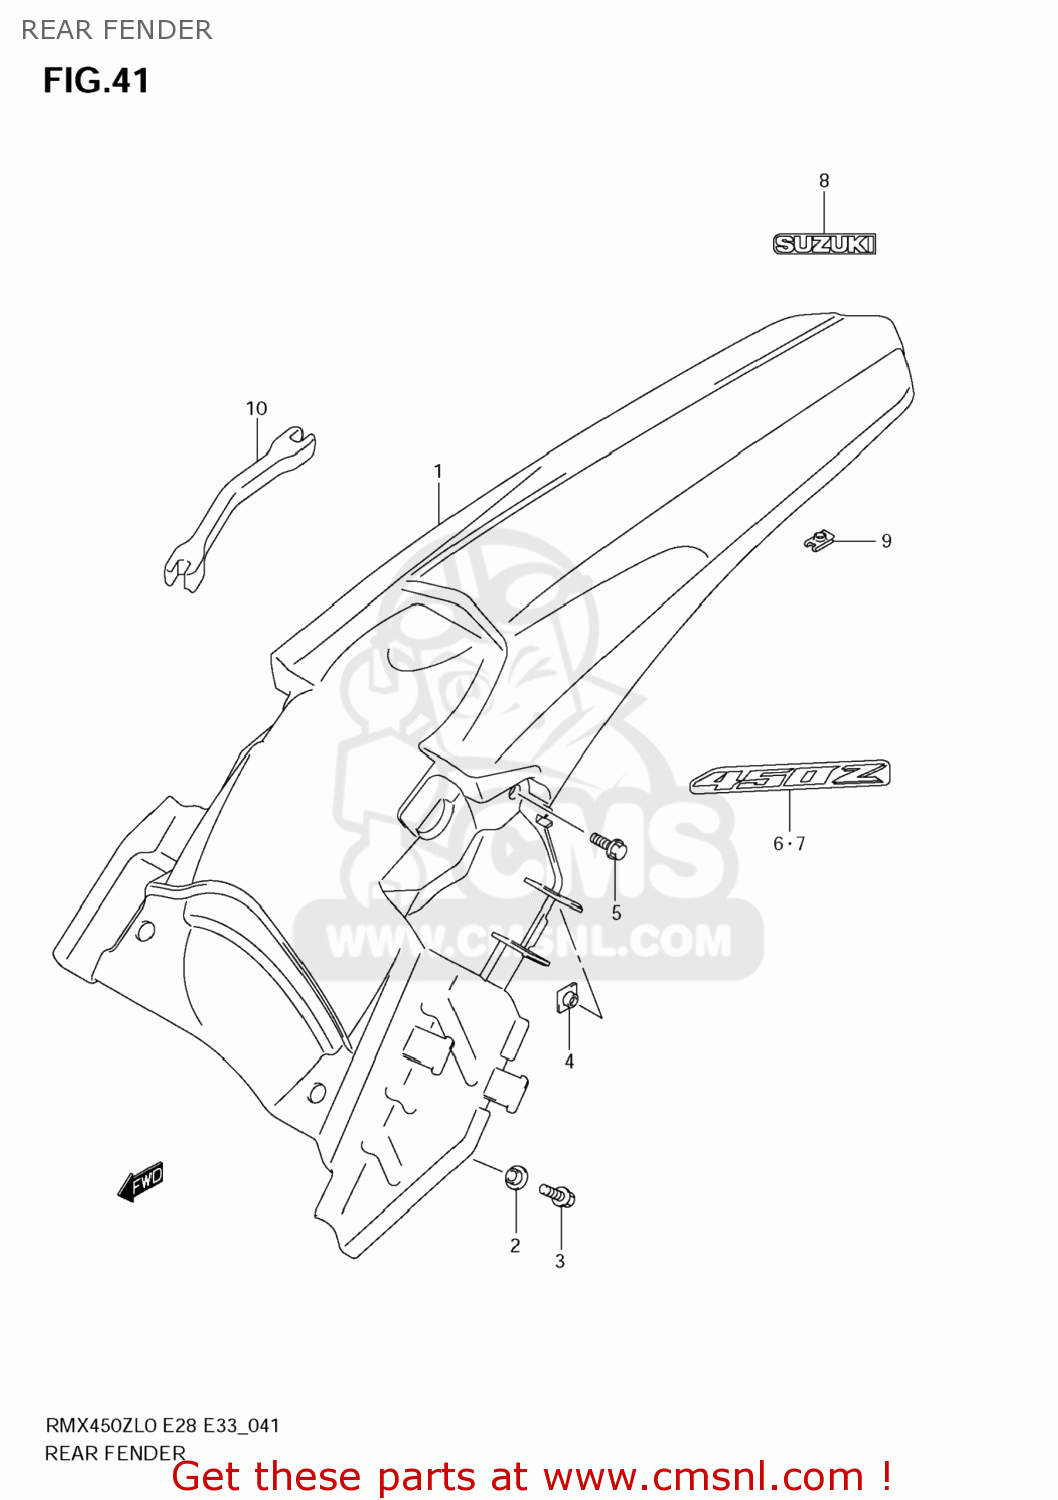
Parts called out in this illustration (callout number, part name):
1	FENDER,RR
2	WASHER,RR FENDER FR
3	BOLT
4	NUT,RR REFLECTOR
5	BOLT(6X16)
6	EMBLEM,RR FENDER,R
7	EMBLEM,RR FENDER,L
8	EMBLEM,SUZUKI
9	NUT
10	OPEN SPANNER(6.4X6.8)
